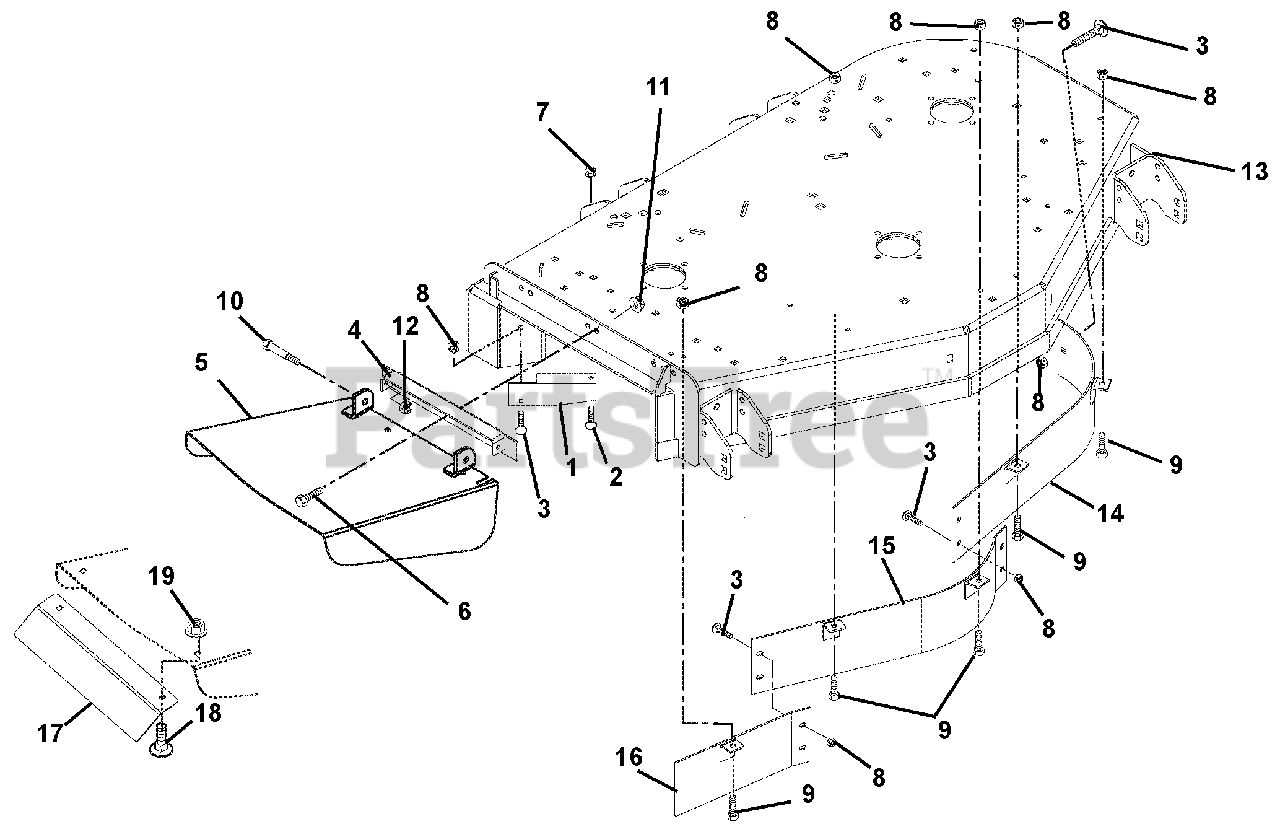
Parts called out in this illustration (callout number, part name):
1	Deflector- 60"
2	Bolt-Round Head Square Neck .38-16 x .75 Grade 5
3	Bolt-Round Head Square Neck .31-18 x .75 Grade 5
4	Weldment, Discharge Chute Bracket
5	Chute-Discharge
6	Bolt-Hex .38-16 x 1.00 Grade 5
7	Nut-Locking-Top-Flange .38-16
8	Nut, Locking-Top-Flange .31-18
9	Bolt, Hex .31-18 x .75 Grade 5
10	Bolt, Shoulder .38-16 x .50 Socket Head
11	Nut, Flange .375-16
12	Nut, Locking-Center .38-16
13	Weldment, 60" Mower Deck
14	Weldment, Upper Baffle Left 60"
15	Weldment, Baffle, Center Front 60"
16	Weldment, Baffle, Right Front 60"
17	Deflector, Chute
18	Bolt, Round Head Square Neck .38-16 x .75 Grade 5
19	Nut, Locking Top Flange .38-16
